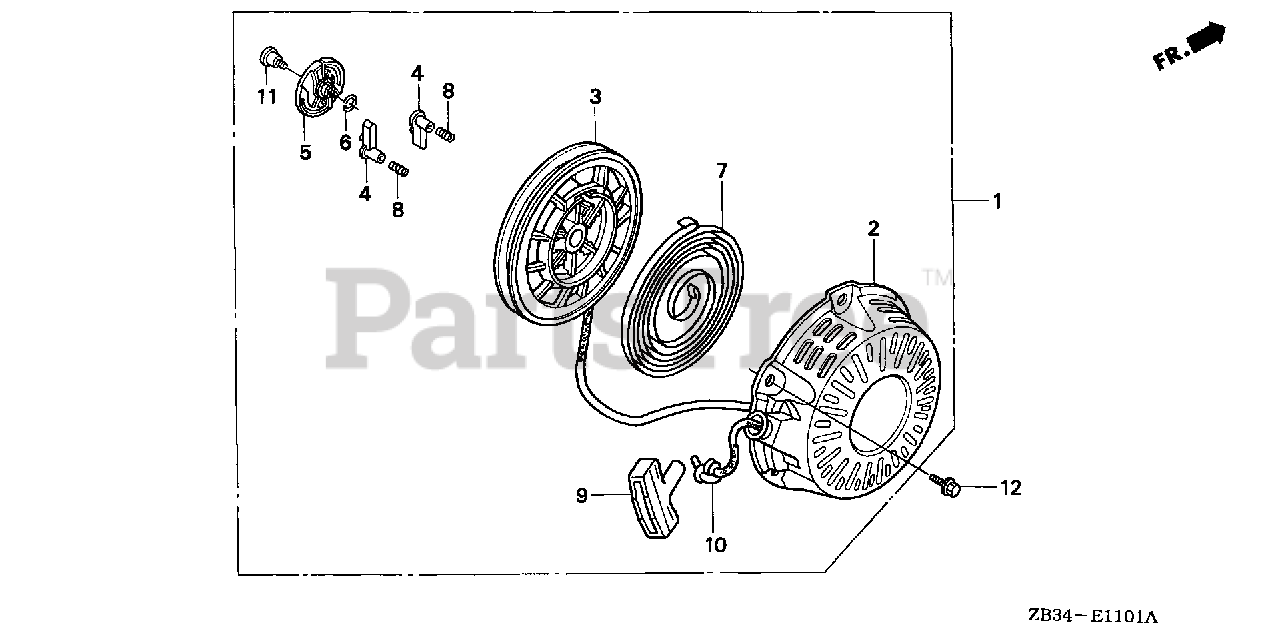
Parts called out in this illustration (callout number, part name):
1	STARTER ASSY., RECOIL *R280* (POWER RED)
1	STARTER ASSY., RECOIL *NH1* (BLACK)
2	CASE, RECOIL STARTER *NH1* (BLACK)
2	CASE, RECOIL STARTER *R8* (BRIGHT RED)
2	CASE, RECOIL STARTER *R280* (POWER RED)
3	REEL, RECOIL STARTER (NATURAL)
4	RATCHET, STARTER
5	GUIDE, RATCHET
6	SPRING, FRICTION
7	SPRING, RECOIL STARTER
8	SPRING, RETURN
9	KNOB, RECOIL STARTER
10	ROPE, RECOIL STARTER
11	SCREW, SETTING
12	BOLT, FLANGE (6X8)
